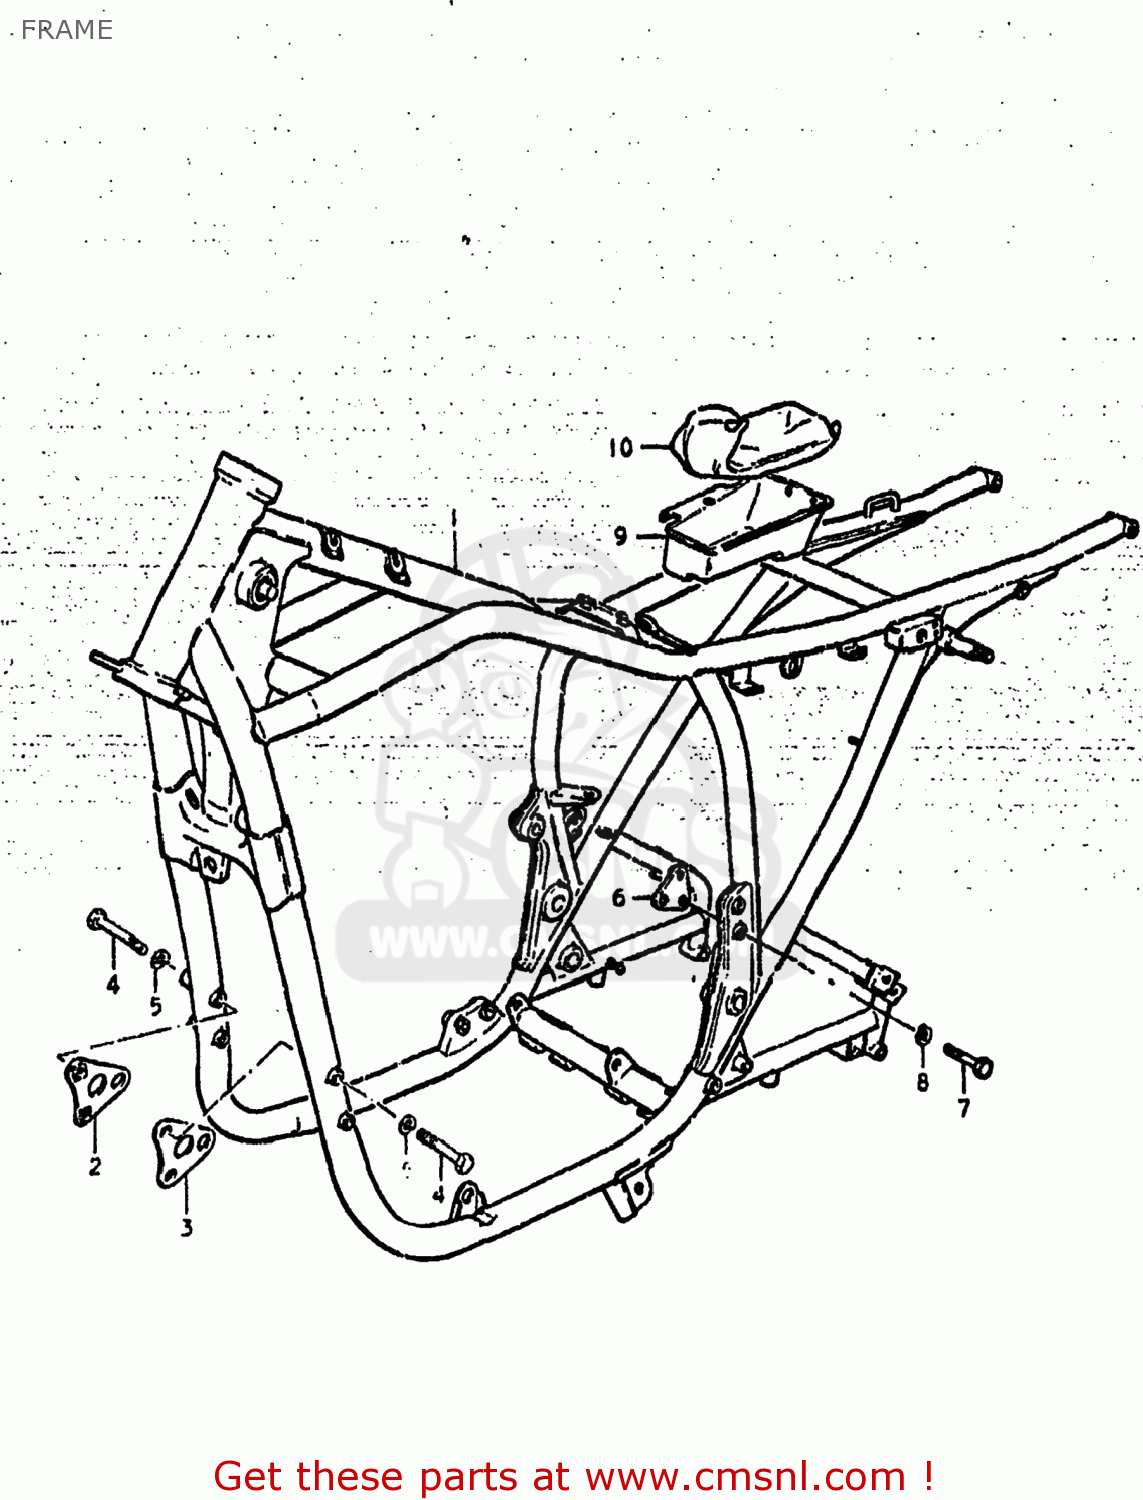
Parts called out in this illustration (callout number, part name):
1	FRAME
2	PLATE,ENGINE MOUNTING
3	PLATE,ENGINE MOUNTING
4	BOLT
5	LOCK WASHER
6	PLATE,ENGINE MOUNTING
7	BOLT 8X40
8	LOCK WASHER
9	HOLDER,TOOL
10	TOOL SET
